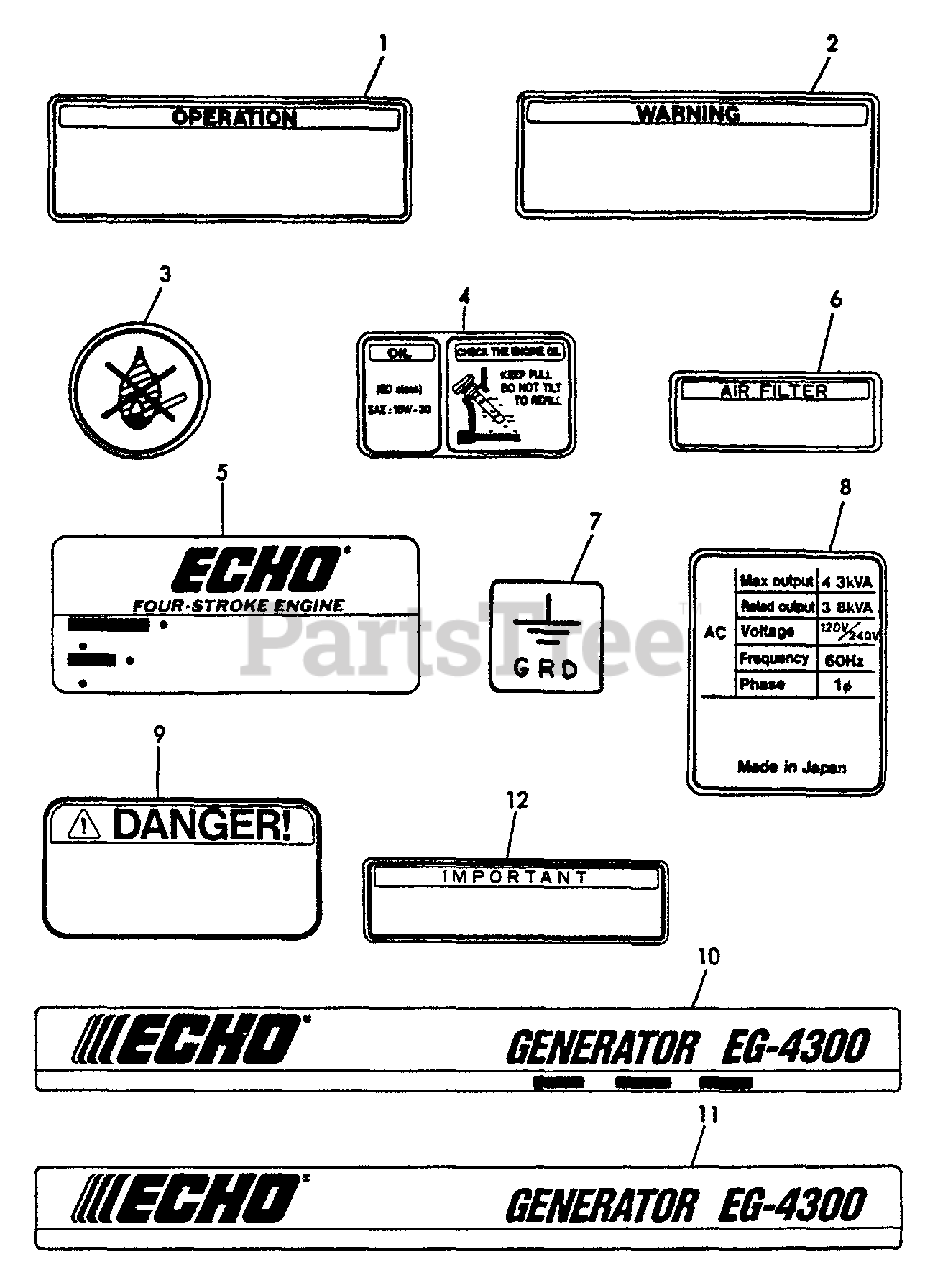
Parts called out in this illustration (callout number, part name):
1	LABEL
2	LABEL - WARNING
3	LABEL, NON FIRE
4	LABEL, OIL
5	LABEL, ECHO
6	LABEL - AIR FILTER
7	LABEL, EARTH
8	LABEL - GENERATOR
9	LABEL DANGER
10	LABEL GENERATOR
11	LABEL GENERATOR
12	LABEL - IMPORTANT
